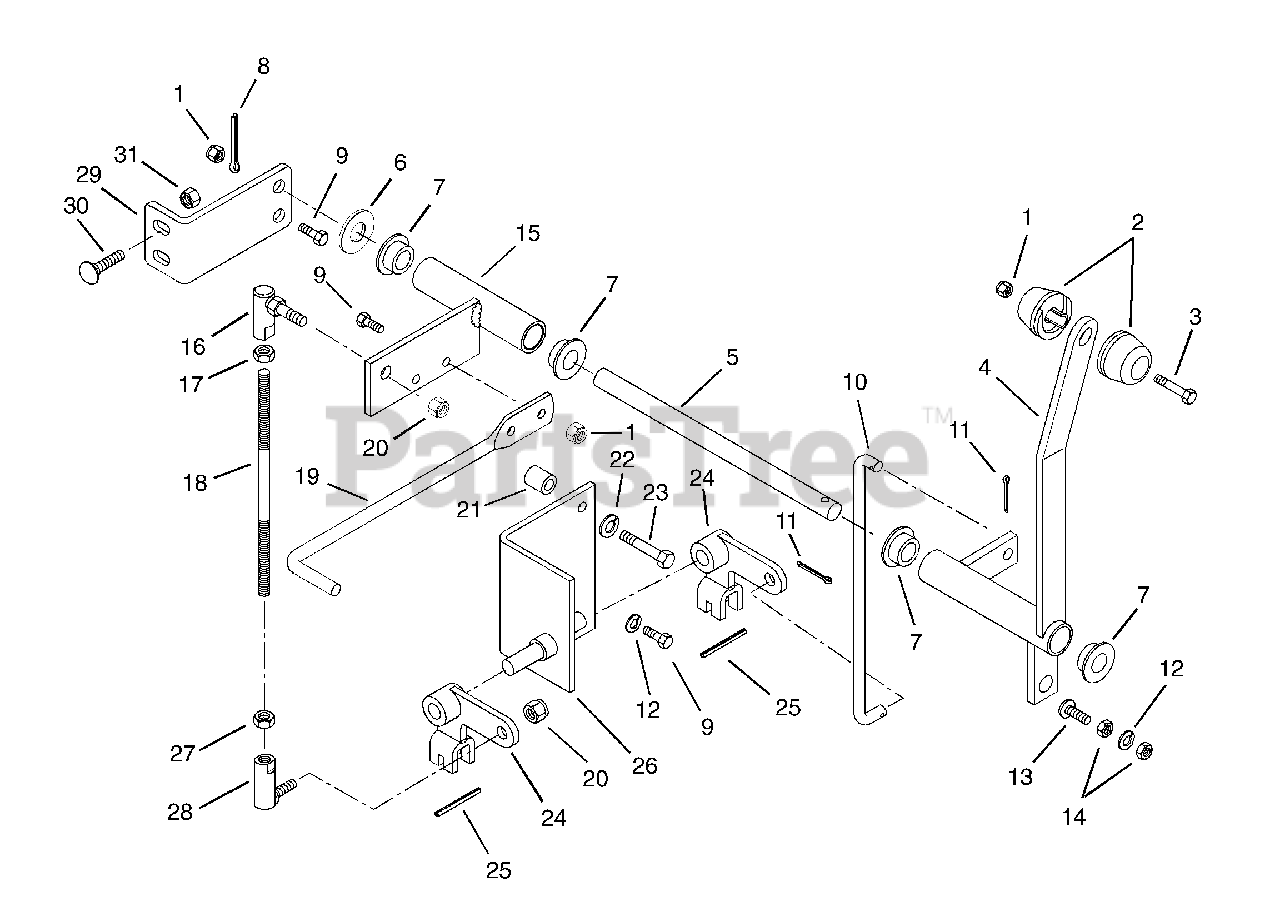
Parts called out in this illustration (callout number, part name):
1	Nut-Locking-Center .25-20
2	Knob, Control
3	Bolt-Hex .25-20 x 1.50 Grade 5
4	Control, Hi-Lo
5	Shaft, Control
6	Washer-Flat-Steel .531 x 1.06 x .095
7	Bushing-Flange .515 x .750 x .745 x 1.00
8	Pin-Cotter .250 x 2.00
9	Bolt-Hex .25-20 x .875
10	Rod, Hi-Lo
11	Pin-Cotter .09 x .75
12	Washer-Locking .25 X .062
13	Screw-Machine .25-20 x 1.25
14	Nut-Hex .250-20
15	Weldment, Differential Lock Control
16	Joint, Steering Ball
17	Nut-Hex .375-24
18	Rod, Lock Control
19	Bar, Foot
20	Nut-Locking-Nylon .38-24
21	Bushing-Sleeve .407 x .625 x .750
22	Washer-Locking .31 x .078
23	Bolt-Hex .31-18 x 2.00 Grade 5
24	Lever, Hi-Lo
25	Pin-Roll .250 x 1.000
26	Bracket, Shift
27	Nut-Jam .38-24 Left Hand
28	Ball Joint-LH
29	Bracket, Angle
30	Bolt, Round Head Square Neck .31-18 x .75 Grade 5
31	Nut-Locking-Center .31-18
